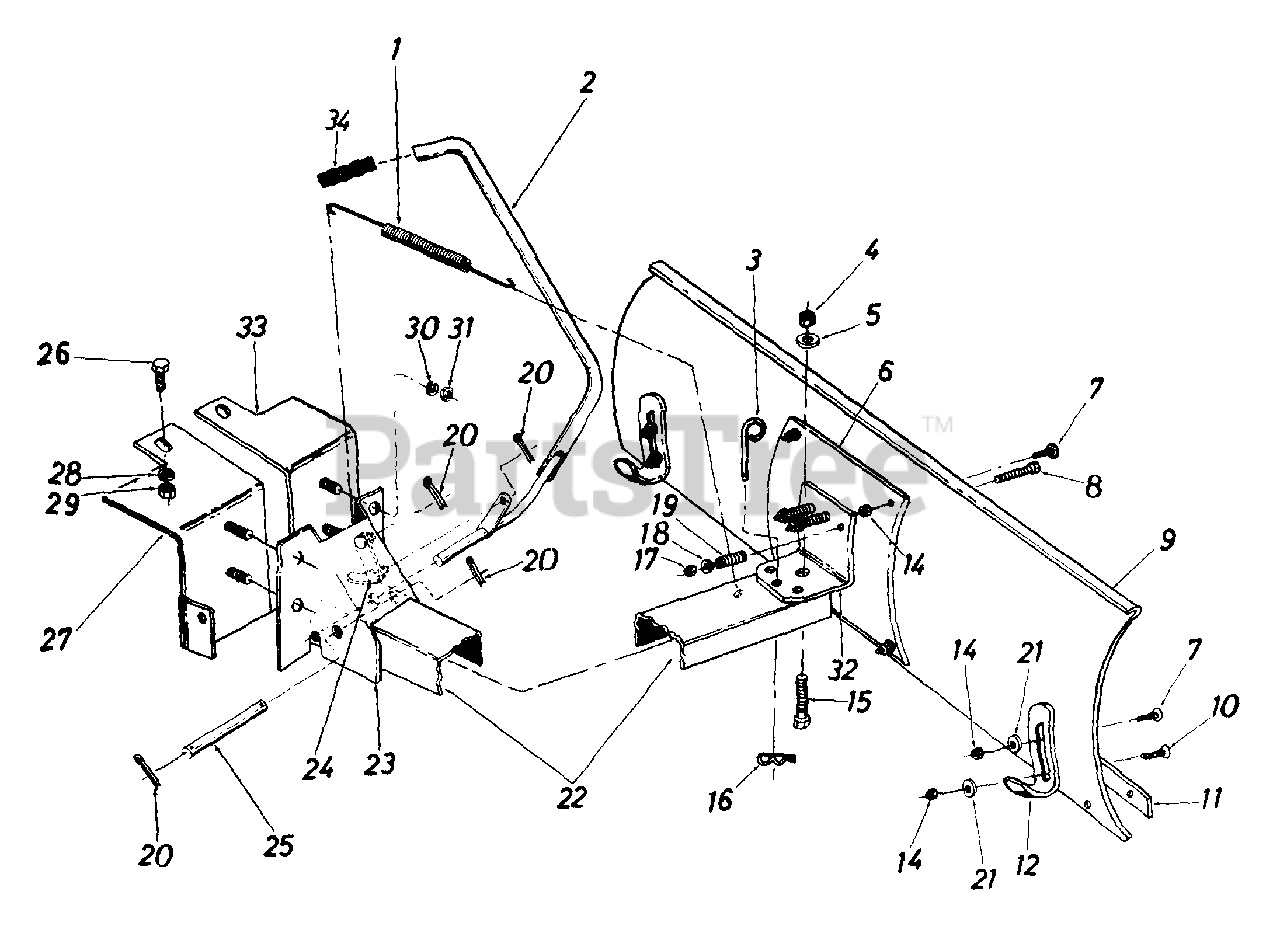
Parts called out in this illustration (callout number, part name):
1	Extension Spring
2	Lift Handle Ass'y.
3	Pivot Lock Pin
4	Hex Cent. L-Nut 1/2-13 Thd.
5	Fl-Wash. 17/32" l.D. x 1.25" Lg.
6	Reinforcement Plate
7	Carriage Bolt 5/16-18 x .75" Lg.
8	Hex Bolt 3/8-16 x 3.75" Lg. Grade 5
9	42" Blade
10	Carriage Bolt 5/16-18 x 1" Lg.
11	42" Wear Plate
12	Shoe Skid
14	Hex Cent. L-Nut 5/16-18 Thd.
15	Hex Bolt 1/2-13 x 1.25" Lg.
16	Int. Cotter Pin
17	Hex Cent. L-Nut 3/8-16 Thd.
18	Fl-Wash. 3/8" I.D.
19	Compression Spring
20	Cotter Pin 1/8" Dia. x 1" Lg.
21	Fl-Wash. 5/16" I.D.
22	Push Bar Channel
23	Pivot Support Bracket
24	Lift Link
25	Channel Pivot Shaft
26	Hex Bolt 3/8-16 x 1" Lg. Grade 5
27	Support Bracket - R.H.
28	L-Wash. 3/8" I.D.
29	Hex Nut 3/8-16 Thd.
30	L-Wash. 3/8" I.D.
31	Hex Jam Nut 3/8-16 Thd.
32	Support Bracket
33	Support Bracket - L.M.
34	Rubber Grip
